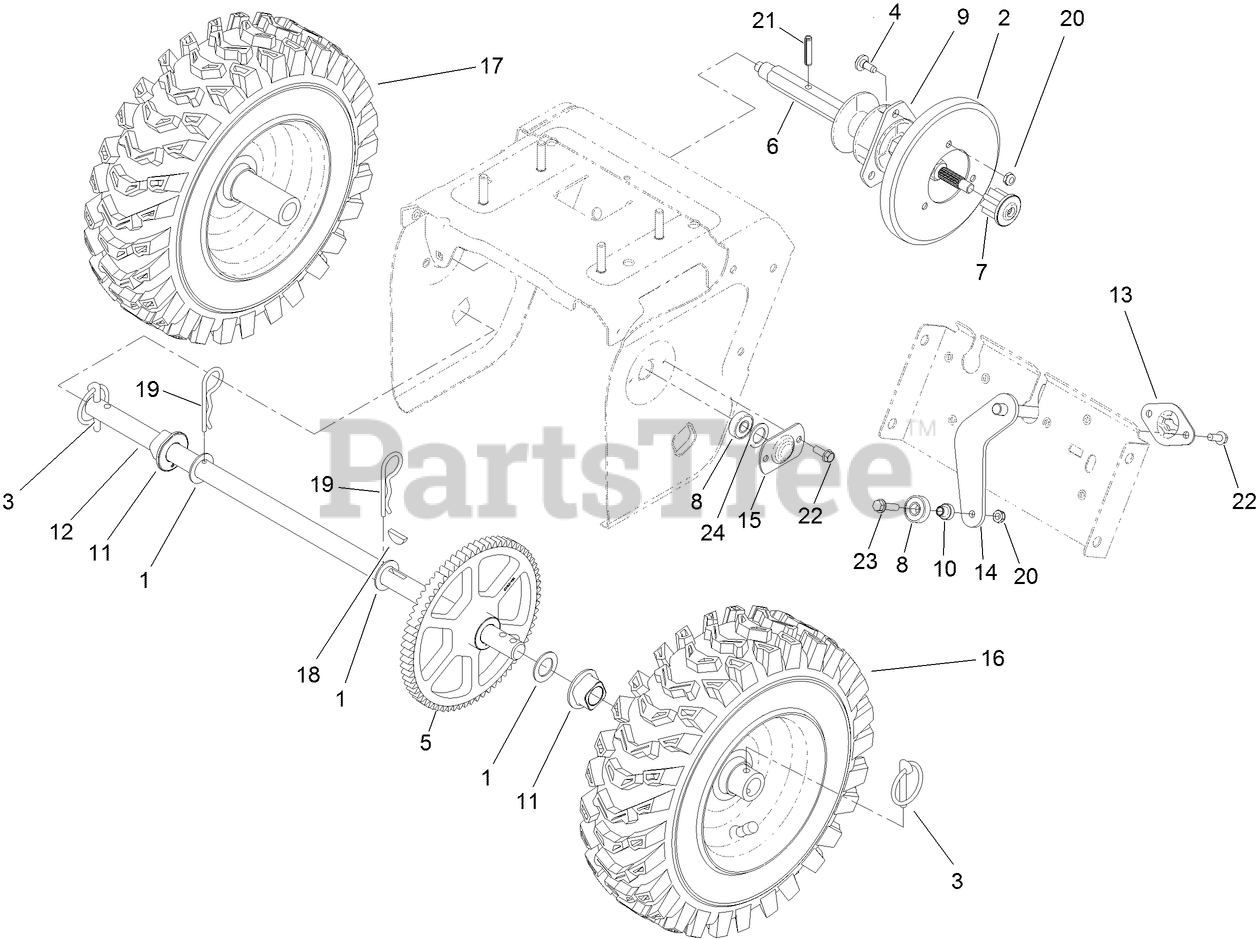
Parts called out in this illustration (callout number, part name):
1	WASHER-THRUST
2	WHEEL-FRICTION
3	KLIK PIN ASM
4	SCREW-SHOULDER
5	GEAR-AXLE
6	SHAFT-HEX
7	GEAR-PINION, 8 TOOTH
8	BEARING-BALL
9	TRUNNION
10	SPACER-PLATE, SHIFT
11	BUSHING-AXLE
13	RETAINER-PLATE, SHIFT
14	SHIFT PLATE ASM
15	RETAINER-BEARING
16	WHEEL AND TIRE LH
17	WHEEL AND TIRE RH
18	KEY-WOODRUFF
19	PIN-HAIR
20	NUT-LOCK, NI
21	PIN-ROLL, SLOTTED
22	SCREW-HWH
23	SCREW-HWHTF
24	WASHER-RUBBER
